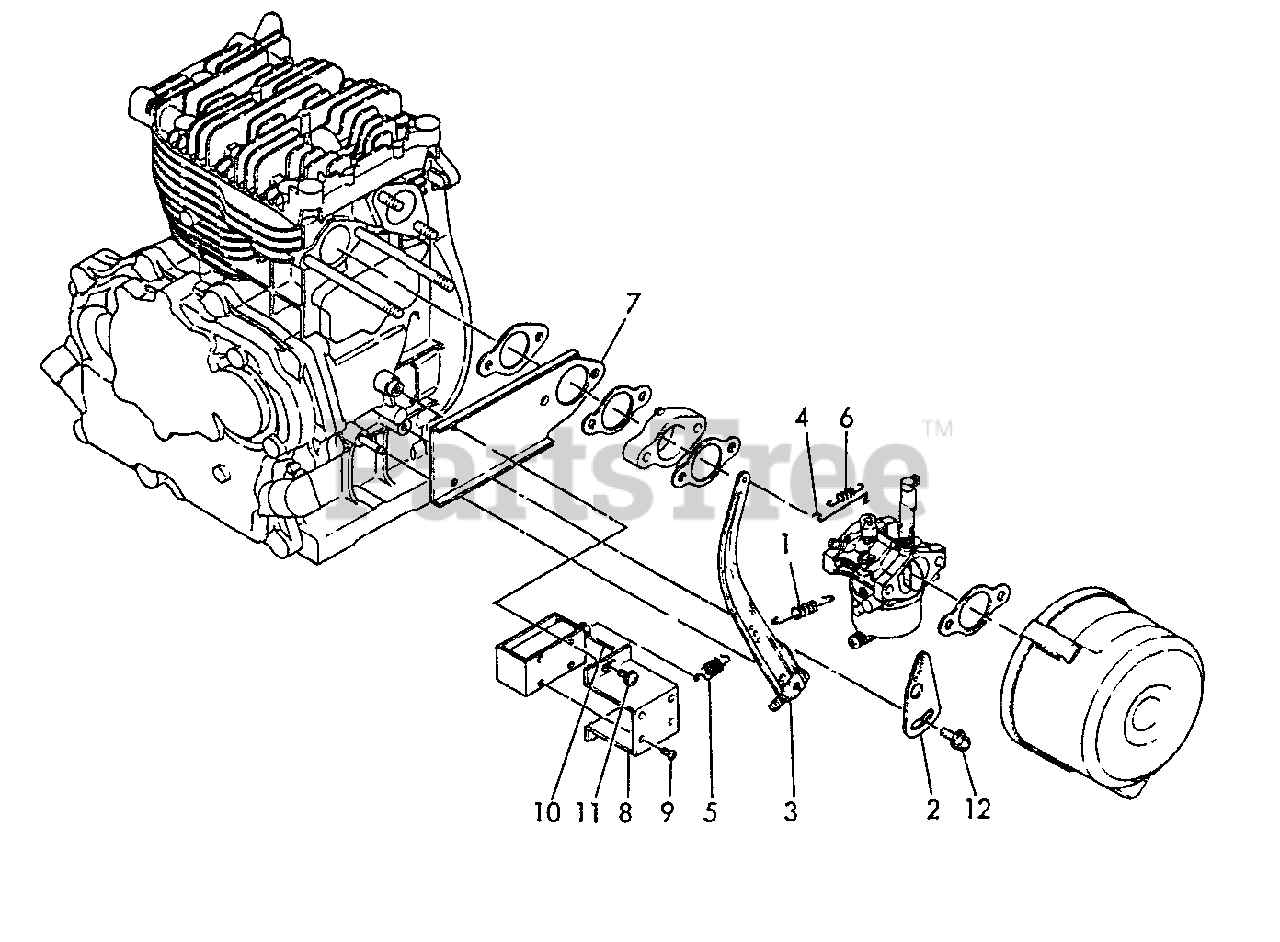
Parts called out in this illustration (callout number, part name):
1	SPRING, REGULATOR
2	HANDLE, REGULATOR
3	LEVER, GOVERNOR
4	LINK, THROTTLE
5	SPRING
6	SPRING
7	MOUNT, SOLENOID
8	HOLDER, SOLENOID
9	SCREW - 3X4
10	PIN, SPLIT - 2.5X20
11	SCREW - 5X10
12	BOLT - 6X8 -- PLATED
